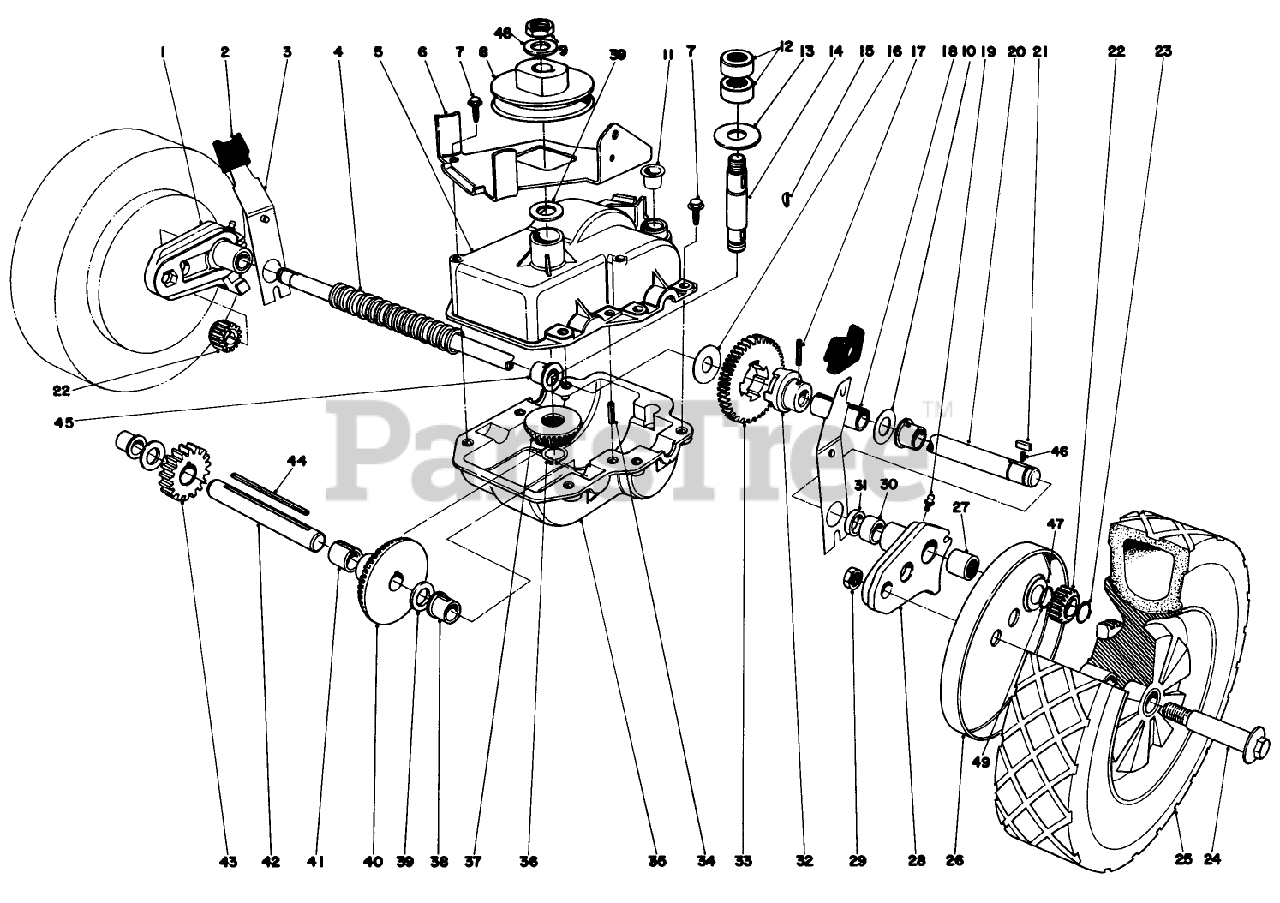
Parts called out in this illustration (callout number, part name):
1	Pivot Arm R.H. (Incl. Ref. #19, 27 & 30-31)
2	KNOB-ARM
3	SP SPRING ARM ASM
4	Cover Drive Shaft
5	Case Upper
6	Bracket-Belt Guide
7	Screw
8	PULLEY
9	Nut
10	WASHER-PLAIN
11	Caplug
12	Bearing
13	Thrust Washer
14	Input Shaft
15	KEY-WOODRUFF
16	WASHER
17	COIL PIN
18	Spacer-Output Shaft
19	FITTING-GREASE
20	Output Shaft
21	KEY RECTANGULAR
22	GEAR-PINION
23	RING-RETAINING
24	BOLT-WHEEL
25	Wheel & Tire Assembly
26	Cover-Wheel
27	Needle Baring
28	Pivot Arm L.H. (Incl. Ref. #19, 27 & 30-31)
29	Nut
30	Bushing
31	Seal
32	ADAPTER DRIVE
33	Gear
34	ROLL PIN 3/16 X 1 IN
35	LOWER GEAR CASE CAST
36	RING-RETAINING
37	Pinion Bevel
38	Botching Shaft
39	WASHER-THRUST
40	BEVEL GEAR
41	Shaft-Pivot
42	Sort Shaft
43	14 T GEAR
44	Key Square
45	Bushing
46	SPRING-COMPRESSION
47	Washer
48	WASHER-FLAT
49	RING-EXT GRIP
